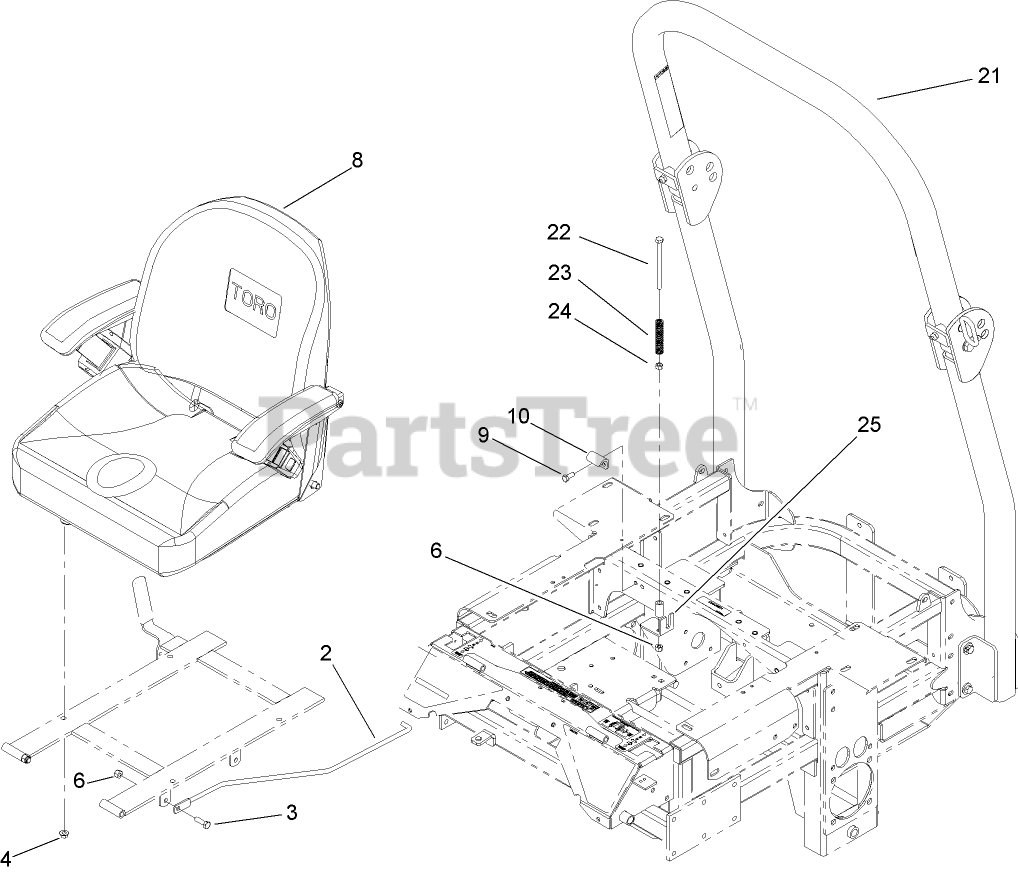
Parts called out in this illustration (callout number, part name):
2	ROD-PROP, SEAT
3	SCREW-HH
4	NUT-HF
6	NUT-LOCK, NI
8	SEAT ASM
9	SCREW-HH
10	Catch-Latch, Seat
21	ROPS KIT
22	SCREW-HH
23	SPRING-SWITCH, SEAT
24	NUT-HEX
25	PLATE-SWITCH, SEAT
